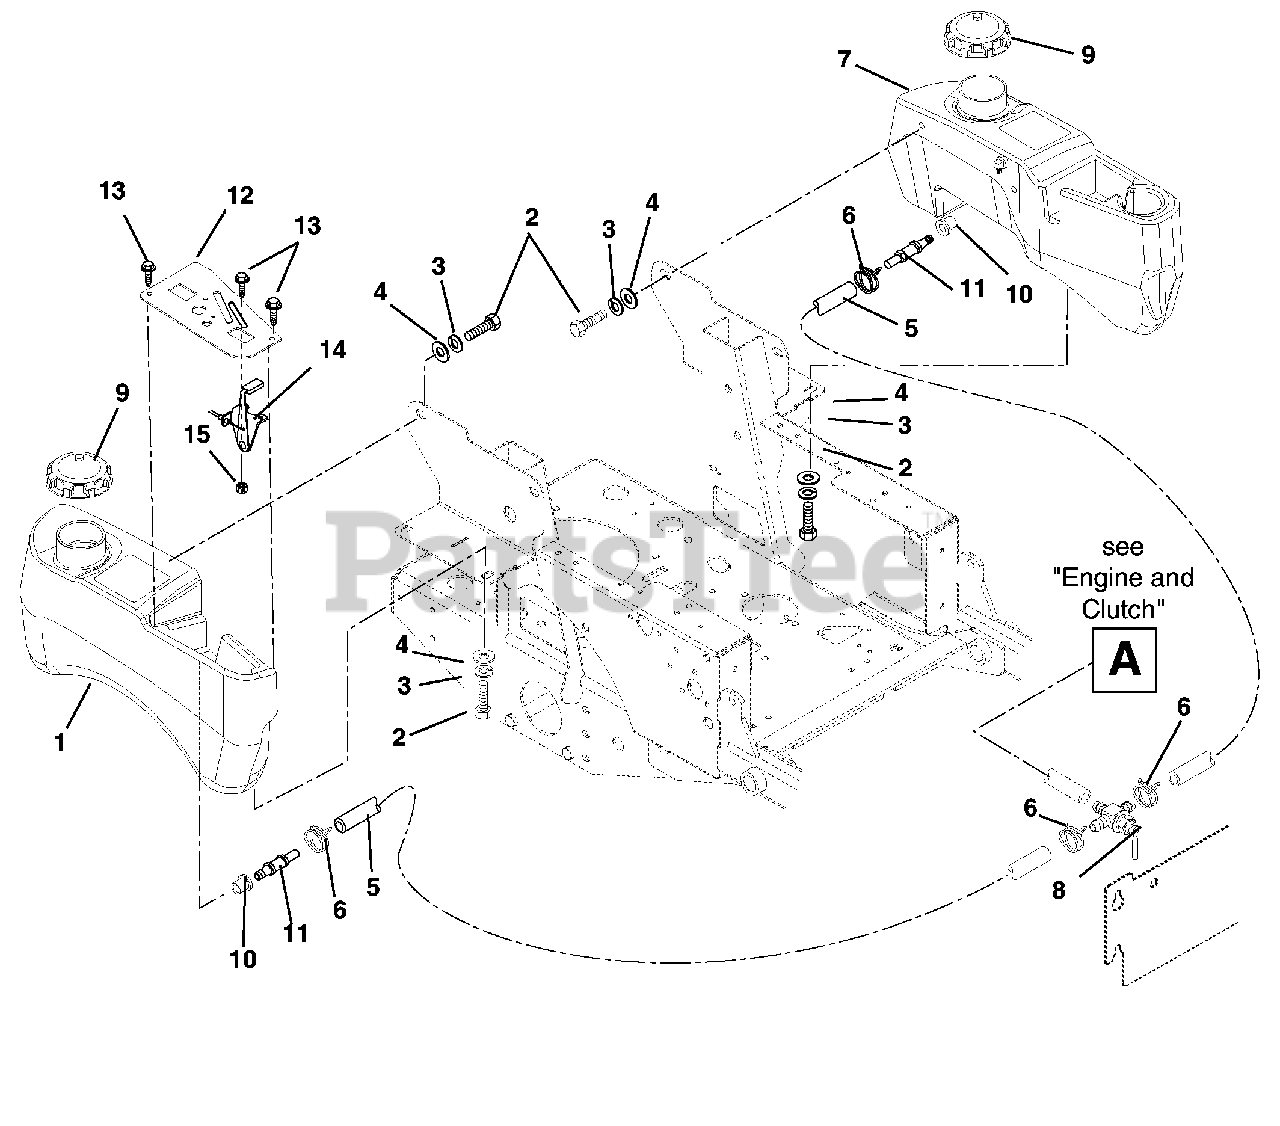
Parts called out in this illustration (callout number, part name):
1	Tank, Gas- Right Hand
2	Bolt, Hex .31-18 x .75 Grade 5
3	Washer, Locking .31 x .078
4	Washer, Flat Steel .38 x .875 x .083
5	Gas Line, Bulk .25" ID x 35"
6	Hose, Clamp
7	Tank, Gas- Left Hand
8	Valve, Fuel
9	Cap, Gas
10	Bushing
11	Fuel Tank Fitting
12	Panel, Control
13	Screw, Machine 10-24 x .50 Hex Washer Head
14	Cable, Throttle / Choke
15	Nut, Locking Nylon 10-24 With Insert
